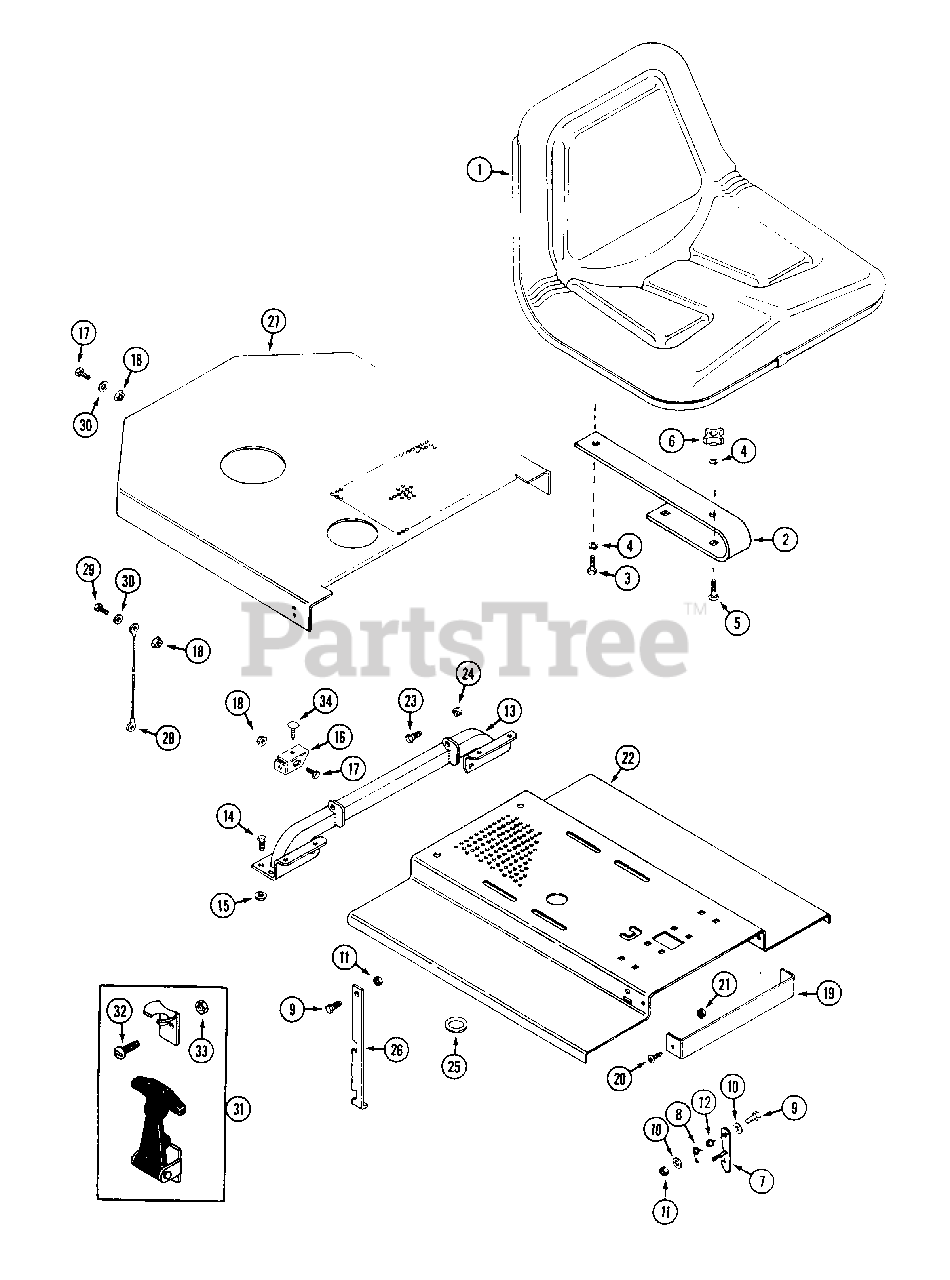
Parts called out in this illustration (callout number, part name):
2	SPRING - seat
3	BOLT - 5/16" - 18 x 3/4"
4	LOCKWASHER - 5/16"
5	BOLT - carriage 6/16" - 18 x 1-1/4"
6	KNOB - seat adjust
7	LATCH lid
8	SPRING - latch
9	BOLT - 1/4" - 20 x 1"
10	WASHER - 1/4"
11	NUT - 1/4" - 20 lock
12	SPACER - latch
13	TUBE - seat support
14	BOLT - 5/16" - 18 x 5/8"
15	NUT - 5/16" - 18 flange lock
16	BRACKET - retainer R.H.
17	BOLT - 1/4" - 20 x 1/2"
18	NUT - 1/4" - 20 flange lock
19	PLATE - filler
20	SCREW - #10 - 32 x 1/2"
21	NUT - #10 - 32 lock
22	LID - seat
23	BOLT - 5/16" - 18 x 1"
24	NUT - lock
25	GROMMET - 1" x 1-3/4"
26	PROP - seat lid
28	LANYARD
29	BOLT - 1/4" - 20 x 3/4"
30	WASHER - .281" x .625
31	LATCH - "T" handle
32	SCREW - #6 - 32 x 1/2"
33	NUT - #6 - 32 lock
34	RETAINER - plastic
